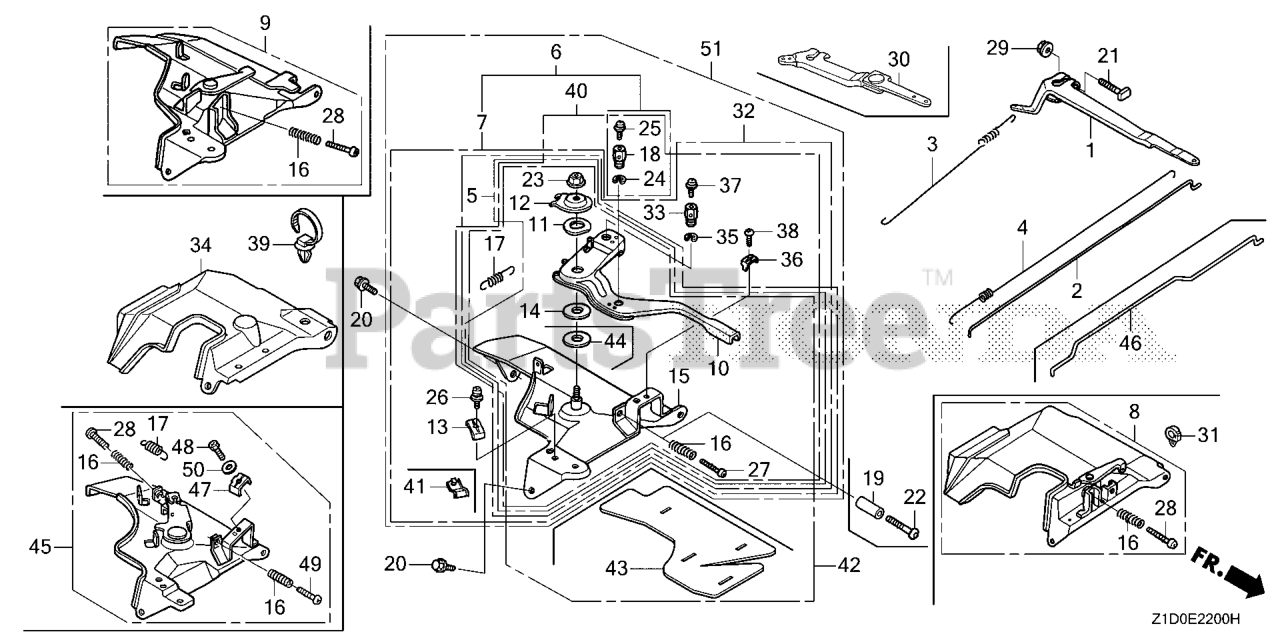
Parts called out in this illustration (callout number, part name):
1	ARM, GOVERNOR
2	ROD, GOVERNOR
3	SPRING, GOVERNOR (L=145.0MM) (WIRE DIAMETER 1.0MM)
4	SPRING, THROTTLE RETURN
7	CONTROL ASSY. (REMOTE)
10	LEVER, CONTROL
11	SPRING, LEVER
12	WASHER, CONTROL LEVER
13	HOLDER, CABLE
14	SPACER, CONTROL LEVER
15	BASE, CONTROL
16	SPRING, CONTROL ADJUSTING Use from Engine SN 2327377.
17	SPRING, CABLE RETURN
19	COLLAR, STOPPER
20	BOLT, FLANGE (6X12) (CT200)
21	BOLT, GOVERNOR ARM
22	SCREW, RECESSED (5X25)
23	NUT, SELF-LOCK (6MM)
26	SCREW, PAN (5X16)
27	SCREW, PAN (5X28)
29	NUT, FLANGE (6MM)
